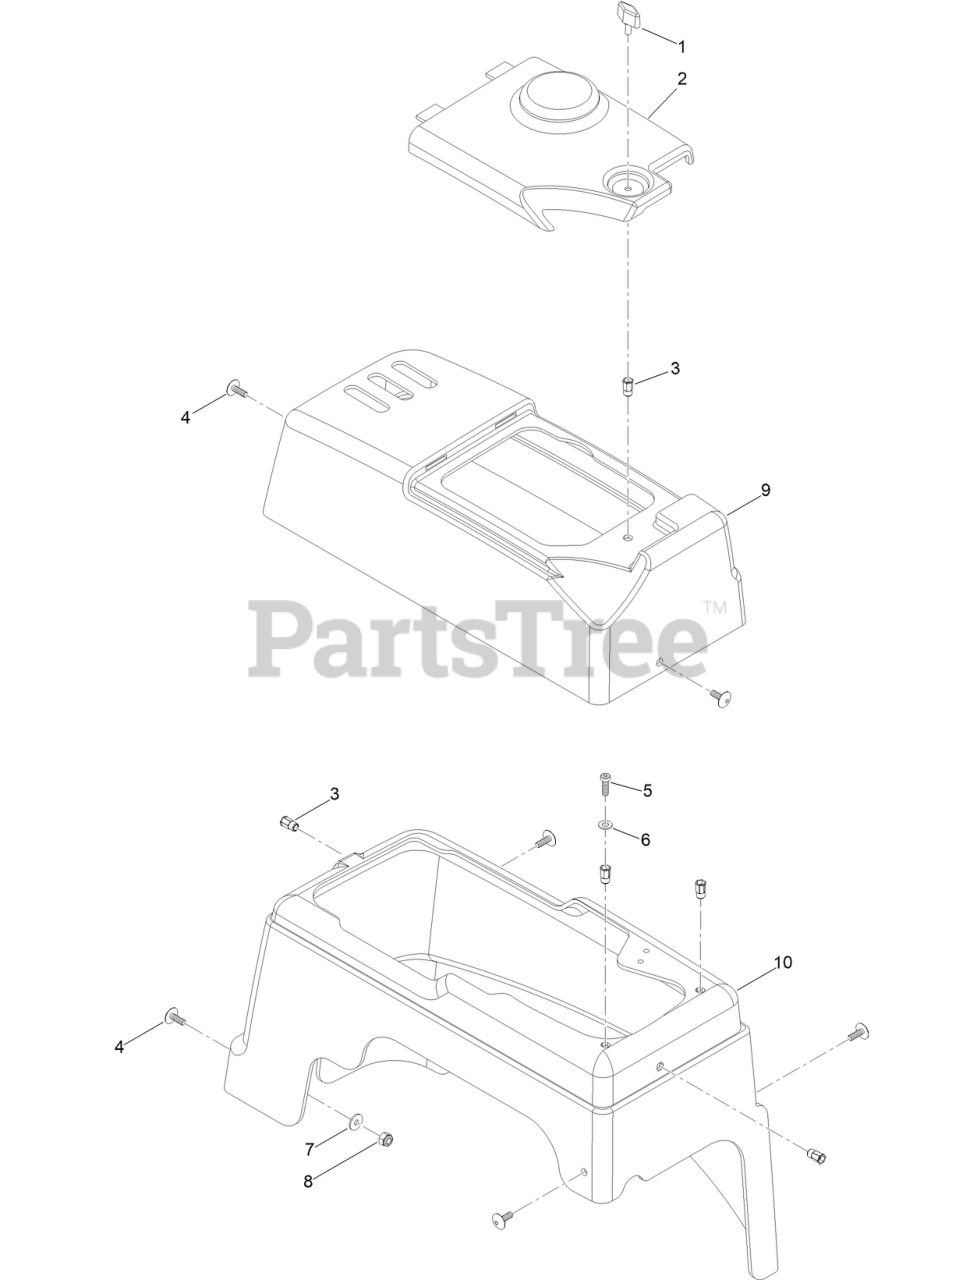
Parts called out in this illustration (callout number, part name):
2	COVER, RH DASHBOARD
3	INSERT-THREADED
6	WASHER
7	WASHER
9	DASHBOARD, RH
10	FAIRING
